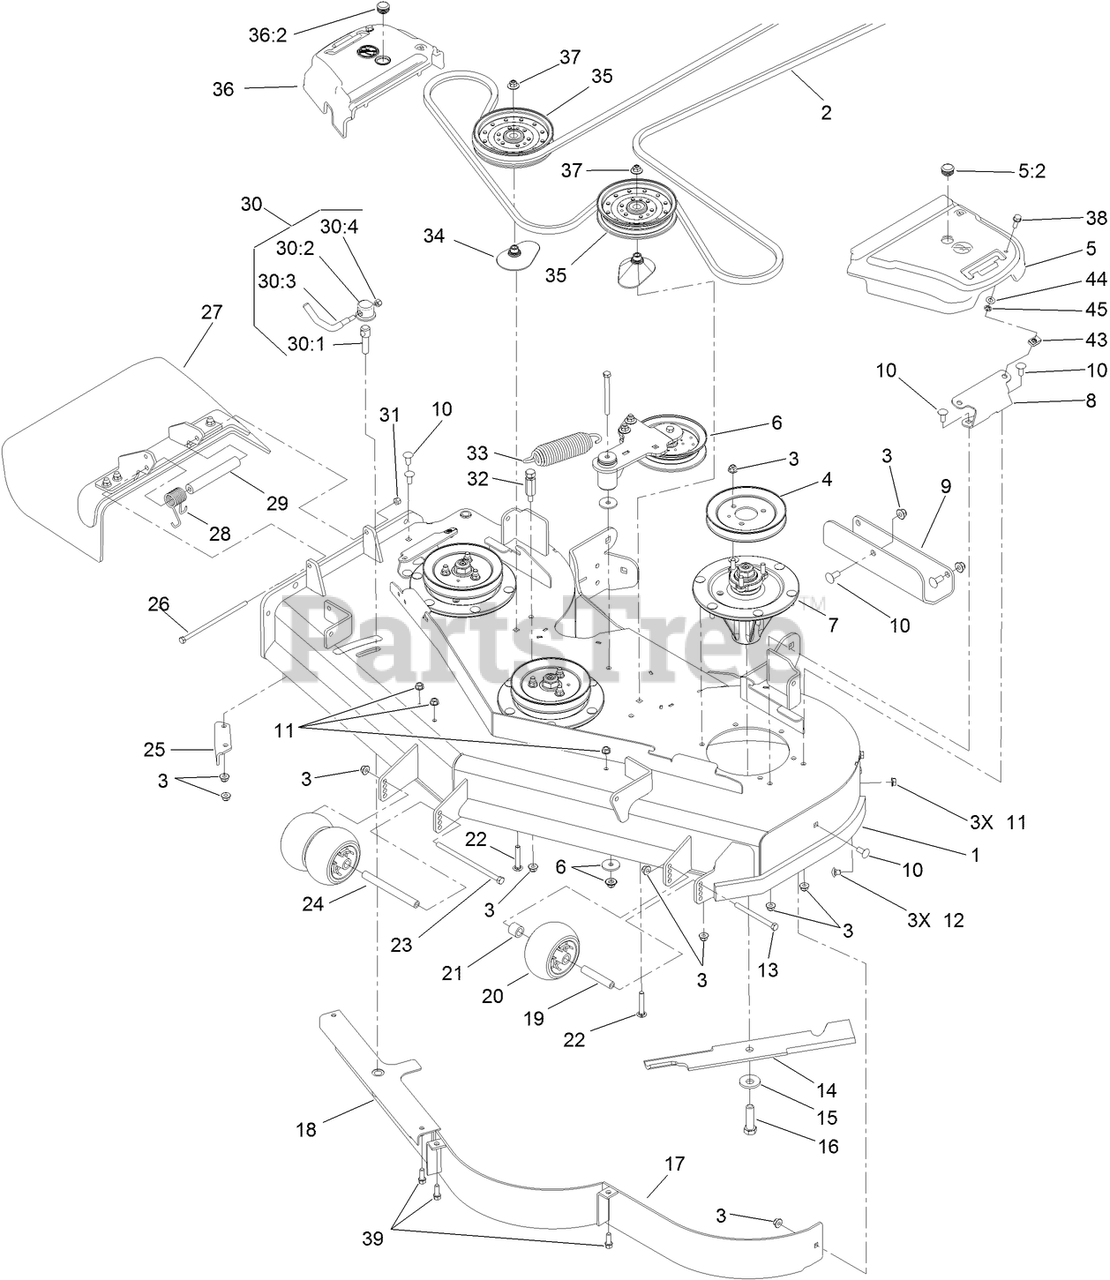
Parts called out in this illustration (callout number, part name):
1	DECK DECAL ASM
2	BELT-V
3	NUT-HF, NI
4	PULLEY
5	LH BELT COVER ASM
5:2	PLUG-PLASTIC
6	IDLER ARM ASM
7	SPINDLE ASM
8	BRACKET-COVER, BELT
9	PLATE-SKID
10	SCREW-CARR
11	NUT-HHF, WHIZ
12	SCREW-CARR
13	SCREW-HH
14	BLADE-18IN, HI FLOW
15	Washer-Blade Bolt, Heavy
16	SCREW-BLADE
17	BAFFLE ASM
18	BAFFLE
19	TUBE-SPANNER
20	ROLLER-SCALP, ANTI
21	TUBE-SPACER
22	BOLT-CARR, SHORT NECK
23	SCREW-HH
24	SPACER-WHEEL
25	BAFFLE-DISCHARGE
26	SCREW-HH
27	RUBBER DEFLECTOR ASM
28	SPRING-TORSION
29	SPACER
30	LEVER ASM
30:1	Screw-Lock
30:2	CAP-LOCK
30:3	Lever-Lock
30:4	NUT-LOCK, NI
31	NUT-LOCK, NI
32	ANCHOR-SPRING, TALL
33	SPRING-EXTENSION
34	SPACER-PULLEY
35	PULLEY-IDLER, FLAT
36	RH BELT COVER ASM
36:2	PLUG-PLASTIC
37	NUT-FLANGE, NI
38	SCREW-HHF
39	SCREW-HWH
43	NUT-U
44	WASHER-THRUST
45	NUT-PUSH
